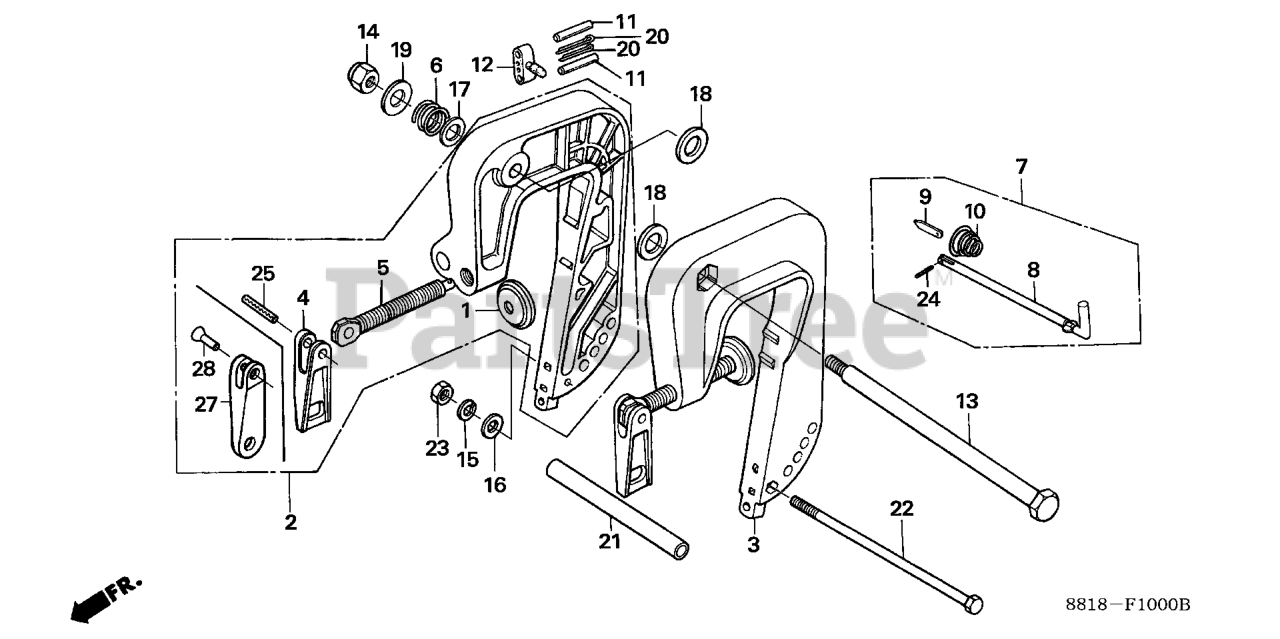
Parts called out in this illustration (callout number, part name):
1	PLATE, PUSH
2	BRACKET, R. STERN *NH282MU* (OYSTER SILVER METALLIC-U)
3	BRACKET, L. STERN *NH282MU* (OYSTER SILVER METALLIC-U)
5	SCREW, CLAMP
6	SPRING, TILT
7	ROD, ADJUSTING
8	ROD, ADJUSTING
9	STOPPER, ROD
10	SPRING, ADJUSTING ROD
11	PIN, SHEAR
12	HOLDER, PARTS
13	BOLT, TILTING
14	NUT, SELF-LOCK (8MM)
15	WASHER, SPRING (6MM)
16	WASHER, PLAIN (6MM) Use from Frame SN 4800713.
17	WASHER, PLAIN (10MM)
18	WASHER (10MM)
19	WASHER (8MM)
20	PIN, COTTER (3MM)
21	COLLAR, DISTANCE (6MM)
22	BOLT, HEX. (6X160)
23	NUT, HEX. (6MM)
24	PIN, SPRING (2X8)
27	GRIP, CLAMP
28	RIVET (4X22.6)
